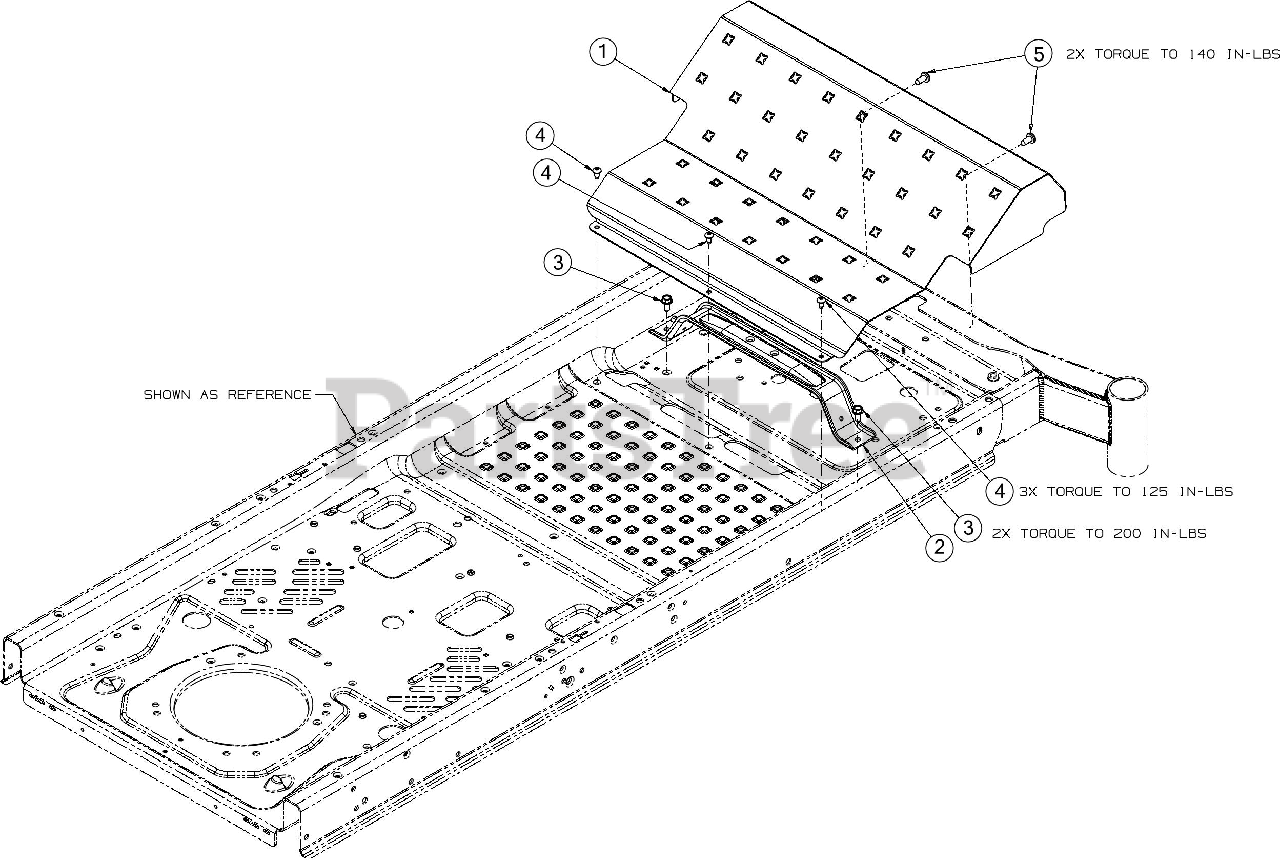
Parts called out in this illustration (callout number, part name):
2	STEERING SUPPORT BRACKET
3	SCREW 5/16-18 x .750
4	SCREW 1/4-20 x .5
5	SCREW 5/16-18 x .750
